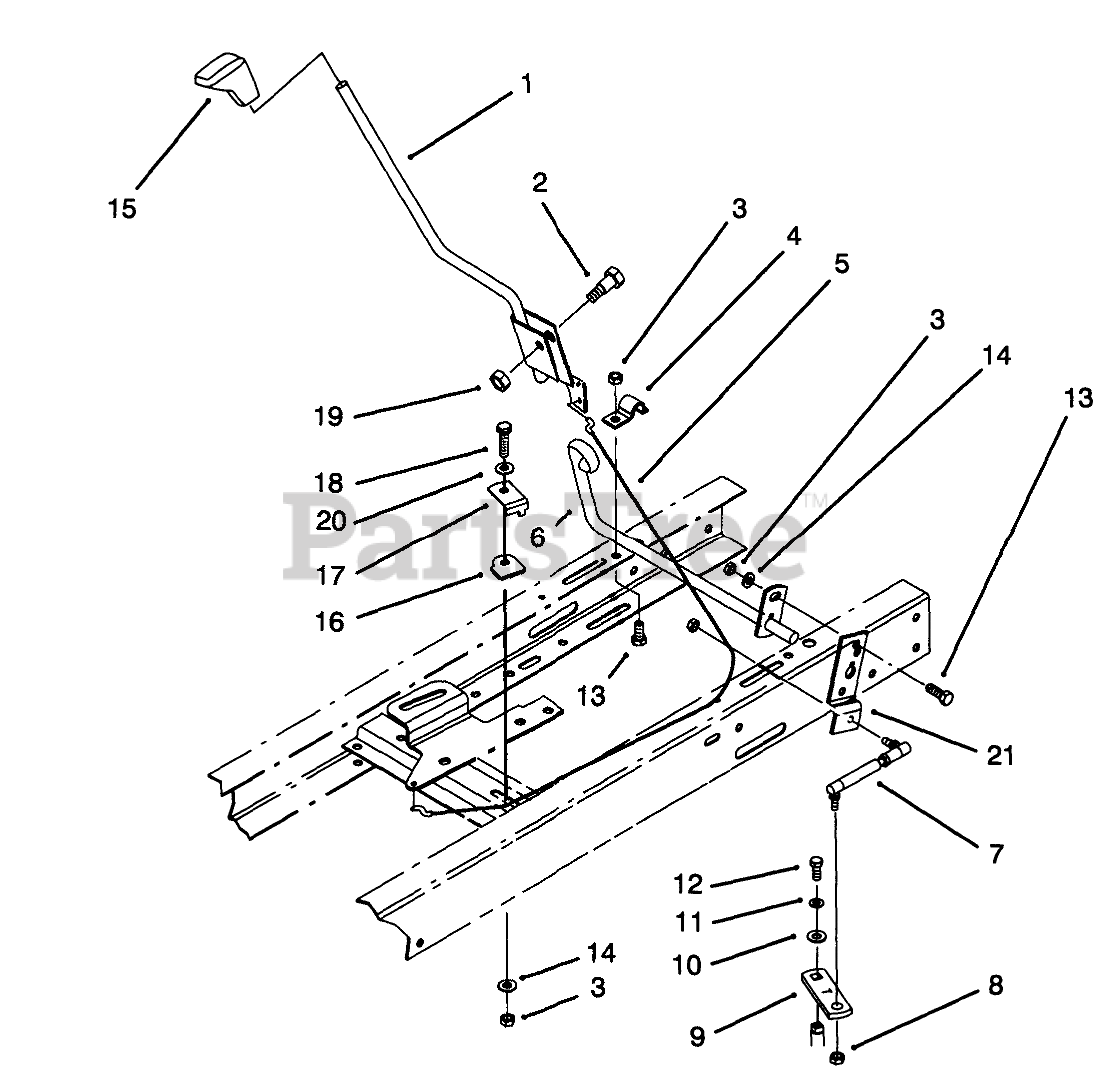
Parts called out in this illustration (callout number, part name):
1	Lever-Shift
2	SHOULDER BOLT
3	NUT-LOCK, NI
4	CLAMP-PIVOT, SHIFT
5	CABLE-CLUTCH
6	SHIFT PIVOT WAB
7	TIE ROD, SHIFT
8	NUT-LOCK
9	LEVER-SHIFT
10	SPACER
11	WASHER-LOCK
12	SCREW-HH
13	SCREW-HH
14	WASHER-PLAIN
15	SHIFT KNOB
16	GUIDE-CABLE
17	KEEPER-CABLE
18	SCREW-CARR
19	NUT-LOCK, NI
20	WASHER-FLAT
21	SHIFT LEVER PIVOTB
